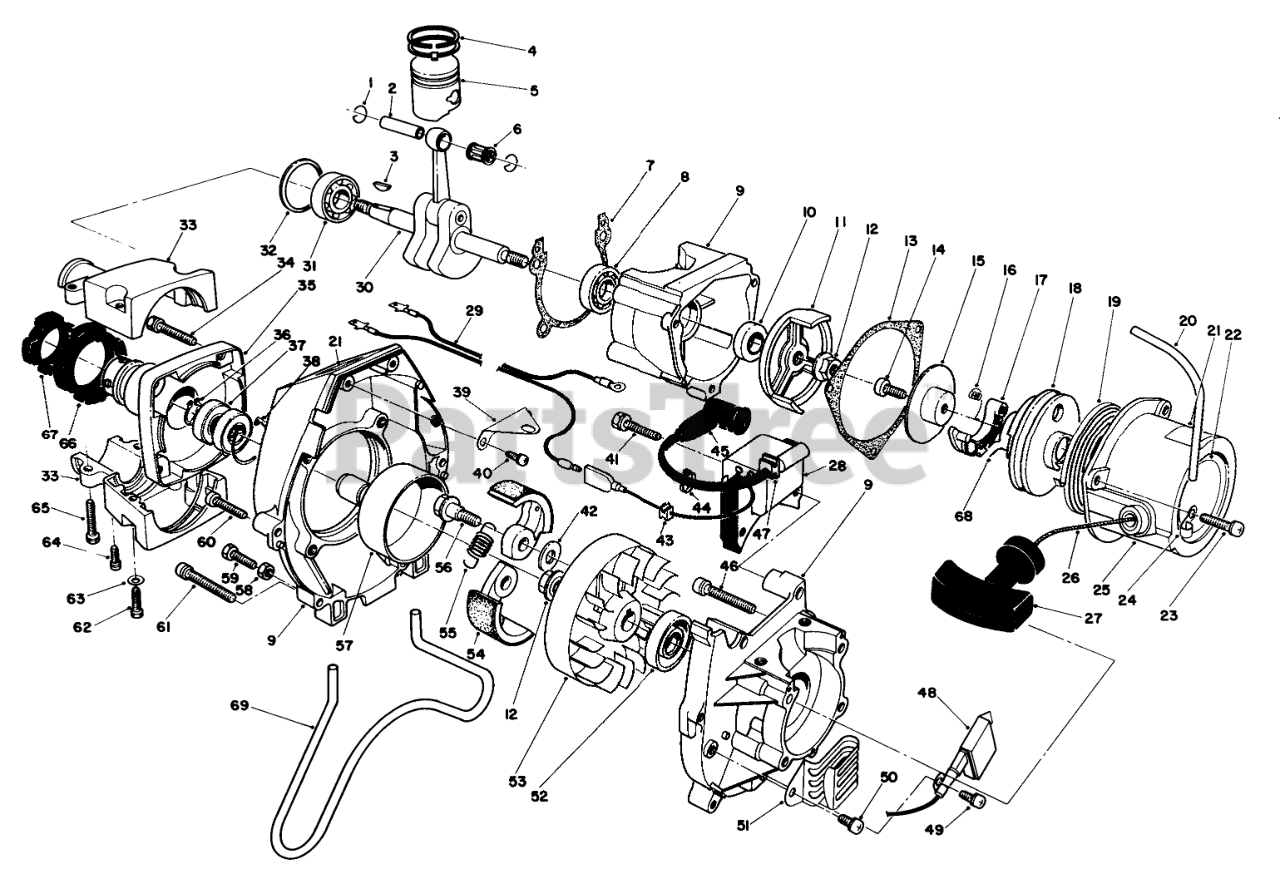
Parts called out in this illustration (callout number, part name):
1	PISTON PIN CLIP
2	PISTON PIN
4	PISTON RING
5	Piston Set (Incl. Ref. #2)
6	NEEDLE BEARING
7	Gasket-Case
8	BEARING
9	Crankcase (Incl. Ref. #46 & 60)
10	OIL SEAL
11	PULLEY, STARTER
13	Gasket-Starter
14	Screw
15	PLATE, FRICTION
16	SPRING, RETURN
17	RATCHET
19	SPRING, SPIRAL
20	PIPE, OVERFLOW
21	DECAL HOT
22	Decal
23	Screw
24	Clamp
25	Recoil Starter (Incl. Ref. #11, 14-19, 26, 27, & 68)
26	Rope-Recoil
27	Knob-Starter
28	IGNITION COIL
29	Lead-Wire
30	Crankshaft (Incl. Ref. #3, & 6)
31	BALL BEARING
32	SNAPRING
33	Holder
34	Bolt/Washer
35	Case-Clutch
36	SNAP RING
37	BALL BEARING
38	SNAP RING
39	Bracket
40	SCREW W/ WASHER
41	BOLT AND WASHER
42	Washer
43	Grommet
45	CAP-PLUG
46	SCREW & WASHER
47	Grommet
48	UNIT,TRANSISTOR
49	SCREW W/ WASHER
50	Screw & Washer
51	Clamp
52	OIL SEAL
53	Flywheel
54	SHOE, CLUTCH
55	Spring
56	CLUTCH BOLT
57	Drum-Clutch
60	Screw
61	Screw
63	Washer
64	SCREW & WASHER
65	BOLT-WASHER/ENG
66	RUBBER, CUSHION (A)
67	RUBBER, CUSHION (B)
68	SPRING, FRICTION
69	TANK GUARD
